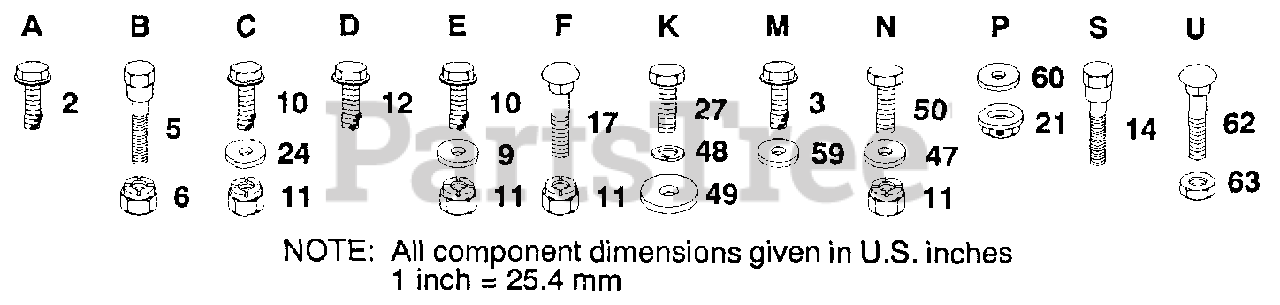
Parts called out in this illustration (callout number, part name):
2	SCREW
3	SCREW GTV
9	WASHER
12	SCREW LT
14	"BOLT,SHOULDER"
17	BOLT
21	PAL NUT LT
24	WASHER
27	BOLT
47	WASHER
48	LOCKWASHER
49	WASHER
50	BOLT
59	WASHER
60	WASHER PM
62	BOLT
